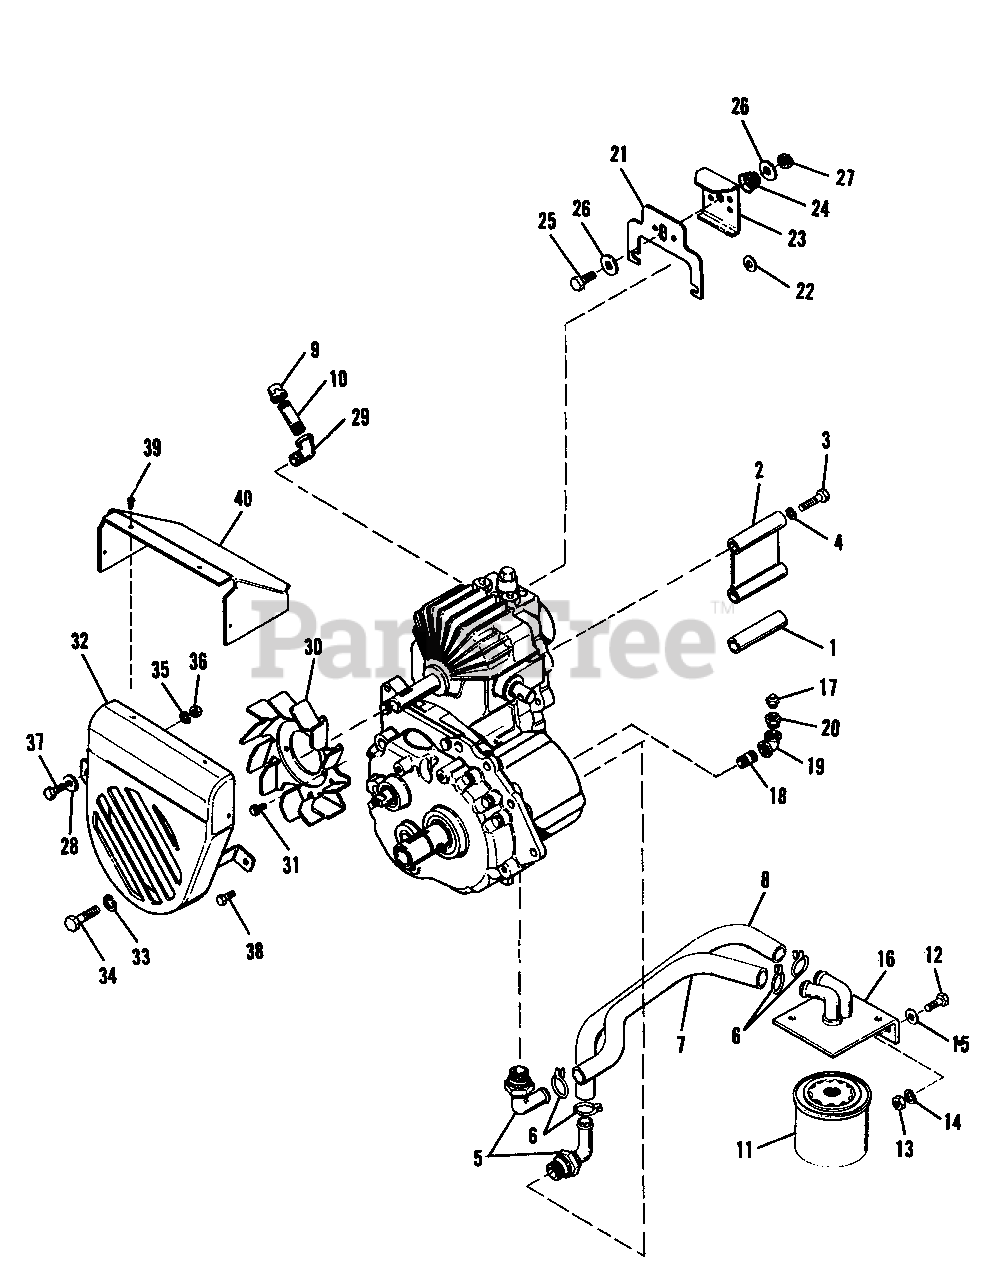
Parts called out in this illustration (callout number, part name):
1	SPACER
3	CAPSCREW, Hex 3/8"-16 x 1-1/8" lg.
4	LOCKWASHER
5	INSERT, Hose
6	CLAMP, Hose
9	CAP, Pipe
10	NIPPLE, Pipe
11	FILTER ASSEMBLY
12	CAPSCREW, Hex, 5/16"-18 x 7/8" lg.
13	NUT, Hex, Full, 5/16"-18
14	LOCKWASHER, 5/16"
15	WASHER, Plain, 5/16"
16	SUPPORT ASSEMBLY, Oil Filter
17	RELIEF VALVE
18	NIPPLE, Pipe
19	ELBOW, Pipe
20	BUSHING, Pipe
23	LATCH, Release
25	CAPSCREW, Hex, 5/16"-18 x 1" lg.
26	WASHER, Plain, 5/16"
27	NUT, Hex, Full, Lock, 5/16"-18
28	WASHER, Plain, 5/16"
29	STEET ELBOW
30	FAN, Pulley
31	SCREW, Hex, Washer Hd. 1/4"-20 x 1/2" lg.
32	SHROUD ASSEMBLY, Fan
33	LOCKWASHER, 3/8"
34	CAPSCREW, Hex, 3/8"-16 x 7/8" lg.
35	LOCKWASHER, 5/16"
36	NUT, Hex, Full, 5/16"-18
37	CAPSCREW, Hex 5/16"-18 x 3/4" lg.
38	SCREW, Hex Thred Forming 5/16" x 1/2" lg.
39	SCREW, Self Tapping #10 x 3/8" lg.
40	DEFLECTOR, Shroud.
